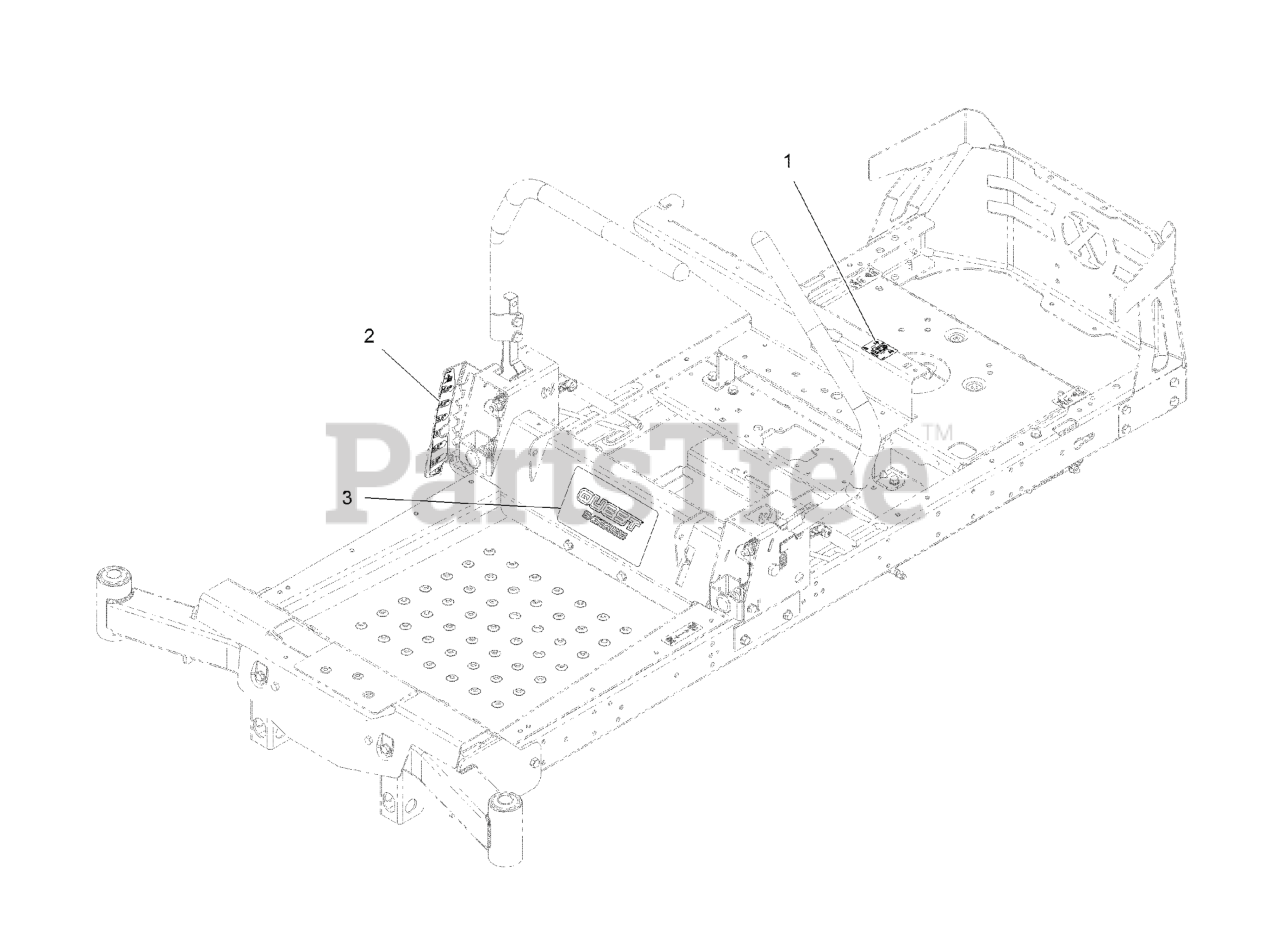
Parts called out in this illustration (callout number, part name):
1	DECAL-SERVICE, CE
2	DECAL-HOC
3	DECAL, QUEST S SERIES
